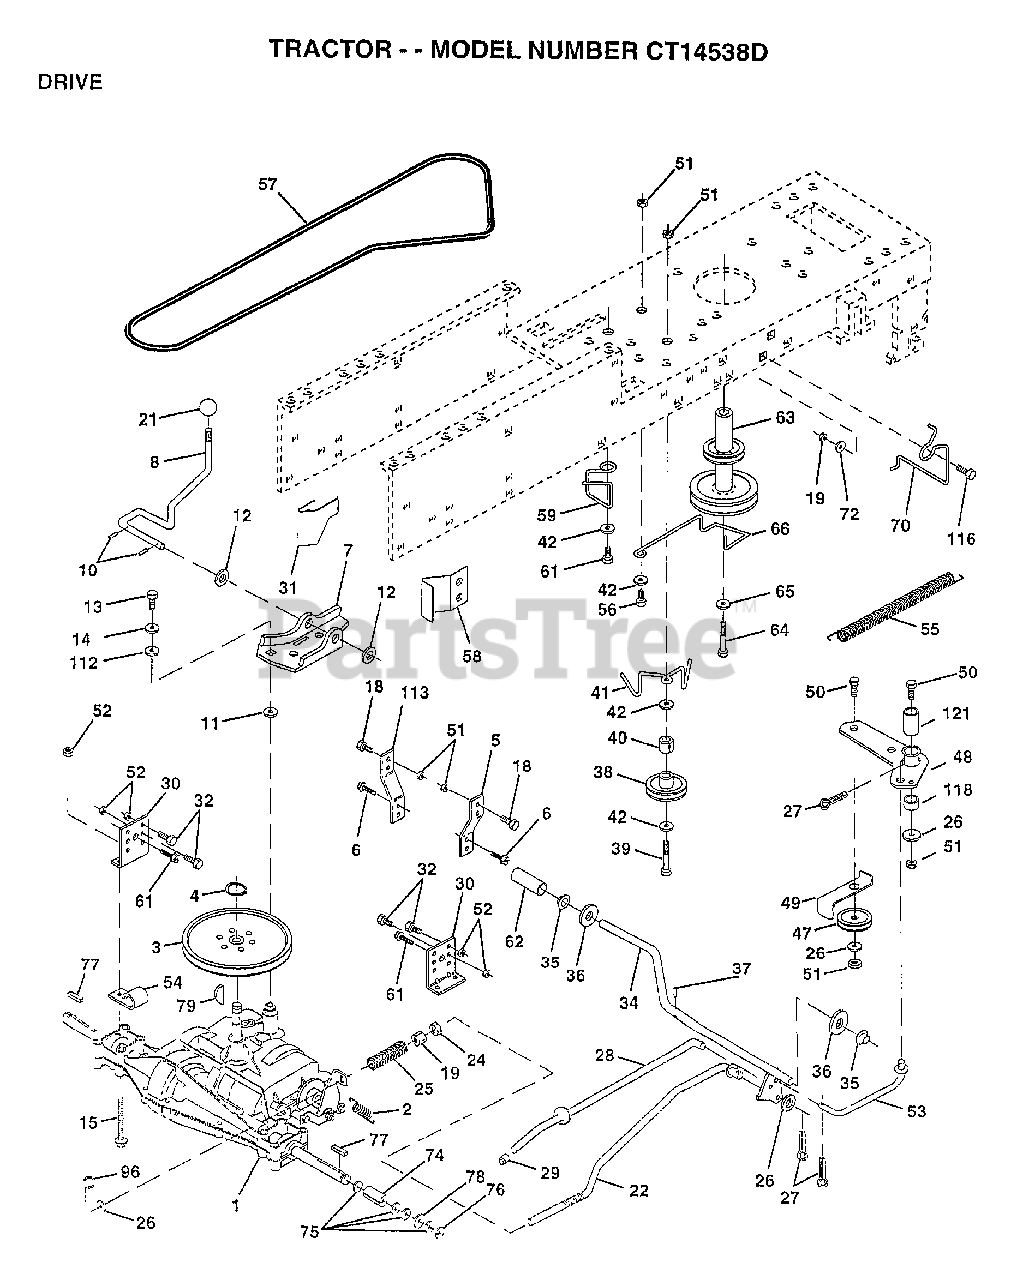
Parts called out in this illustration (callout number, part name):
1	TRANSAXLE, PEERLESS
2	SPRING.BRAKE.RETU
3	PULLEY TRANS
5	STRAP TORQUE
6	SCREW
8	SHIFT ROD
10	PIN COTTER 1/8
11	WASH-SHFT PLT LT
12	WASHER
13	BOLT.1/4-28.W/PAT
14	LOCKWASHER
15	BOLT.HX.FLG.5/16
18	BOLT
19	NUT
21	KNOB T (1/2-HOLE)
22	BRAKE ROD
24	NUT
25	SPRING ROD LT
26	WASHER
27	COTTER PIN
28	ROD.BRAKE.PARK.LT
29	PLUNGER CAP T
30	TRANSAXLE MTG BKT
31	"KEEPER,BELT LH T"
32	BOLT
34	SHAFT ASM-PEDAL F
35	NYLON BEARING
36	WASHER LT
38	PULLEY.IDLER.FLAT
39	BOLT
40	SPACER T
42	WASHER
48	BELLCRANK ASM
49	RETAIN BELT
53	"LINK, CLUTCH T"
54	CLIP T
55	"SPRING, RETURN LT"
58	"KEEPER,BELT RH T"
59	KEEPER BELT CNTSP
61	SCREW
62	PEDAL COVER T
63	PULLEY.ENGINE
64	BOLT
65	LOCKWASHER
66	KEEPER-BELT
70	KEEPER BELT ENG
72	WASHER
74	SPACER AXLE
75	WASHER
76	E-RING LT
77	SQUARE KEY
78	WASHER
96	RETAINER M
112	WASHER LT
113	"STRAP,TORQUE"
116	BOLT RDHD 3/8-16
118	SPACER-BELLCRANK
121	NYLINER-CLUTCHING
